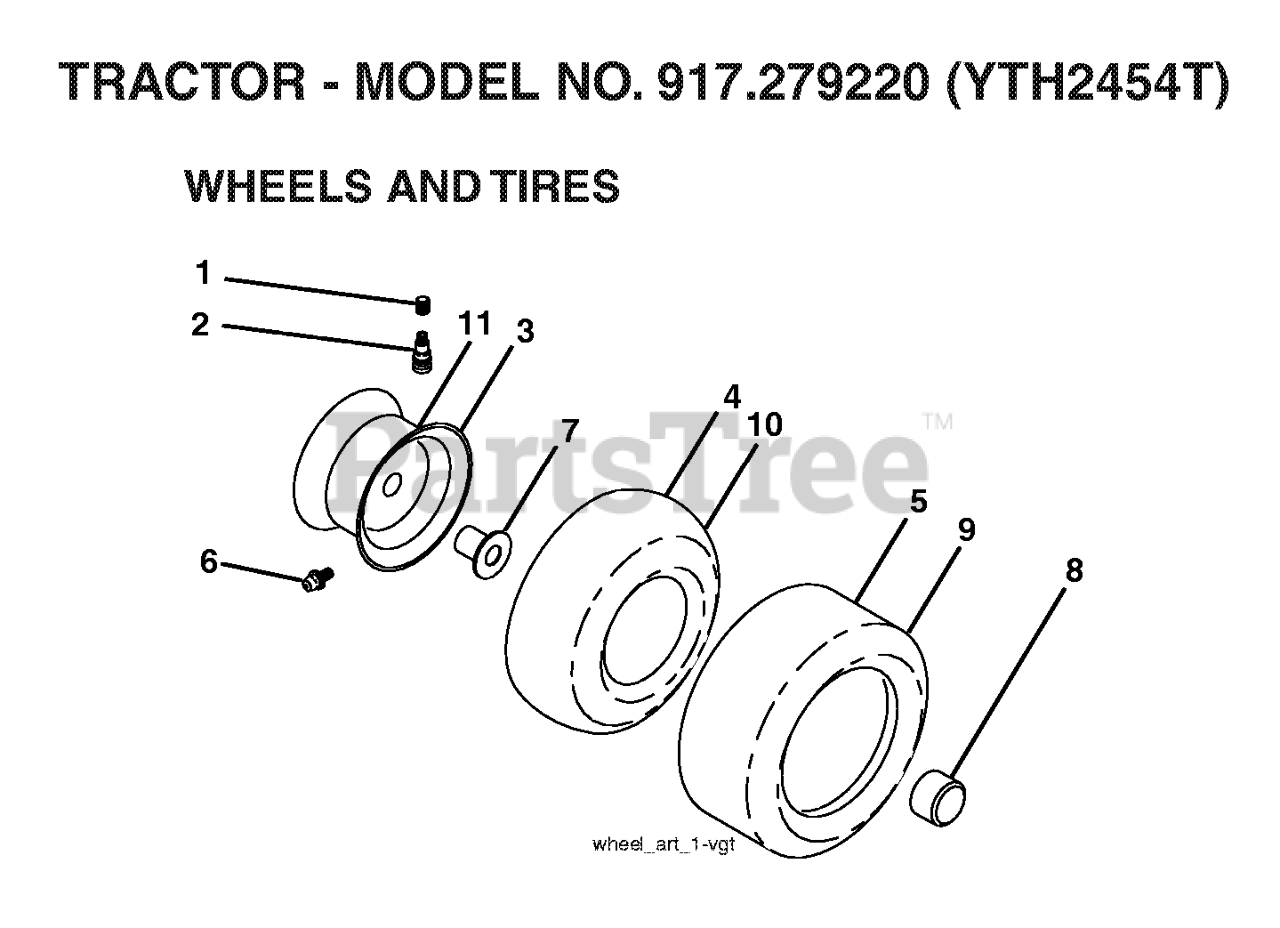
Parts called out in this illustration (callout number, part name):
2	VALVE STEM LT
3	RIM ASM 6" FRONT SILVER
4	TUBE.16X6.5/7.5-8
5	TIRE HEAVY DUTY
6	FITTING LT.
7	BEARING.FLANGE
8	CAP, AXLE BLK
9	TIRE.TS.20X10-8
10	TUBE.23X9.5-12
11	RIM ASM 8" REAR SILVER
